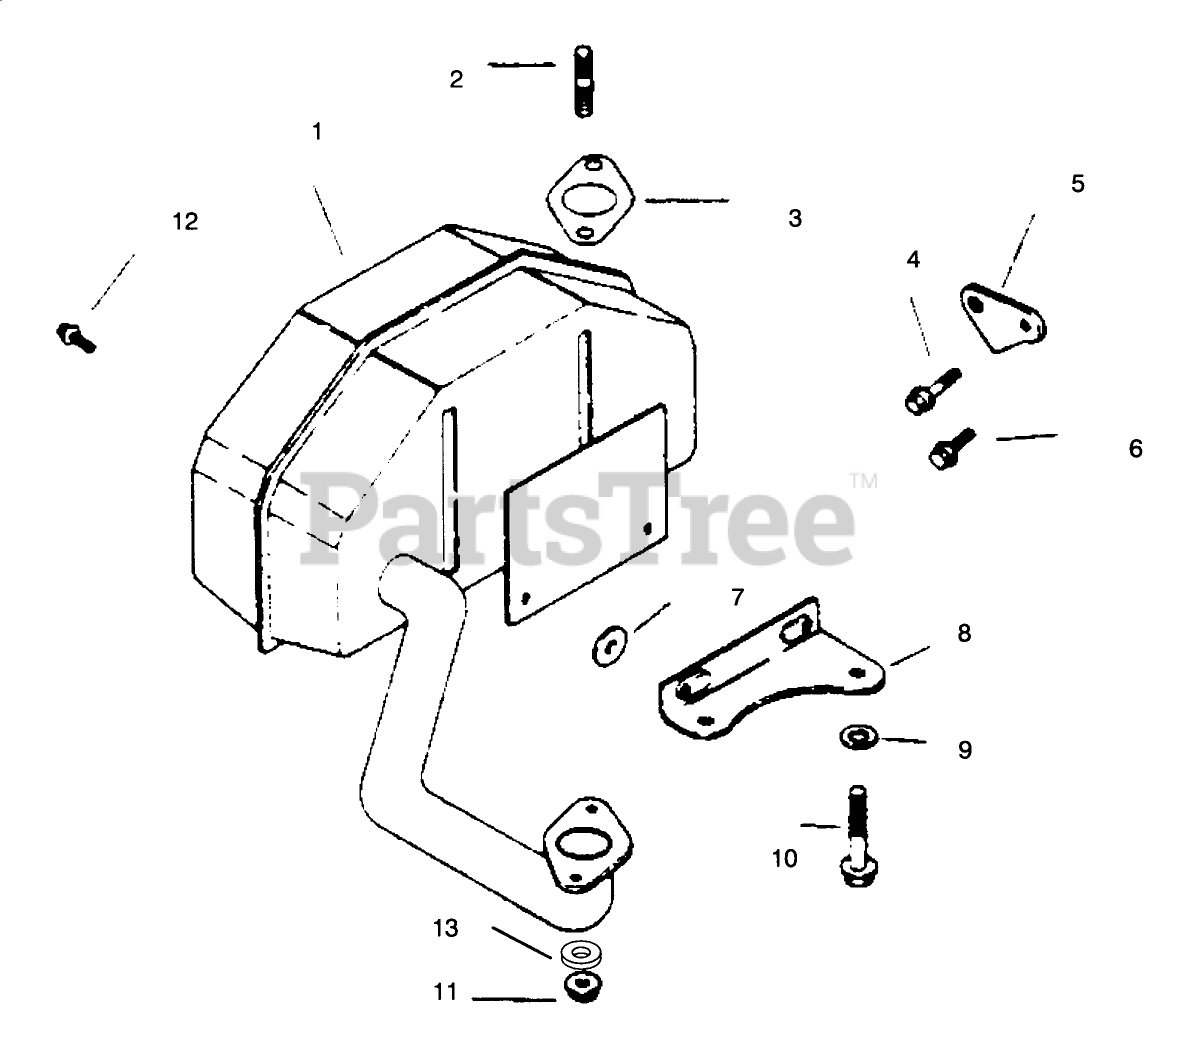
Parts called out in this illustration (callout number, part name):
1	Muffler
2	Stud
3	Gasket-Exhaust
4	Screw
5	Strap-Lifting
6	Screw
7	Washer
8	Bracket-Muffler
9	Washer
10	Screw
11	Nut
12	Screw
13	WASHER-LOCK
